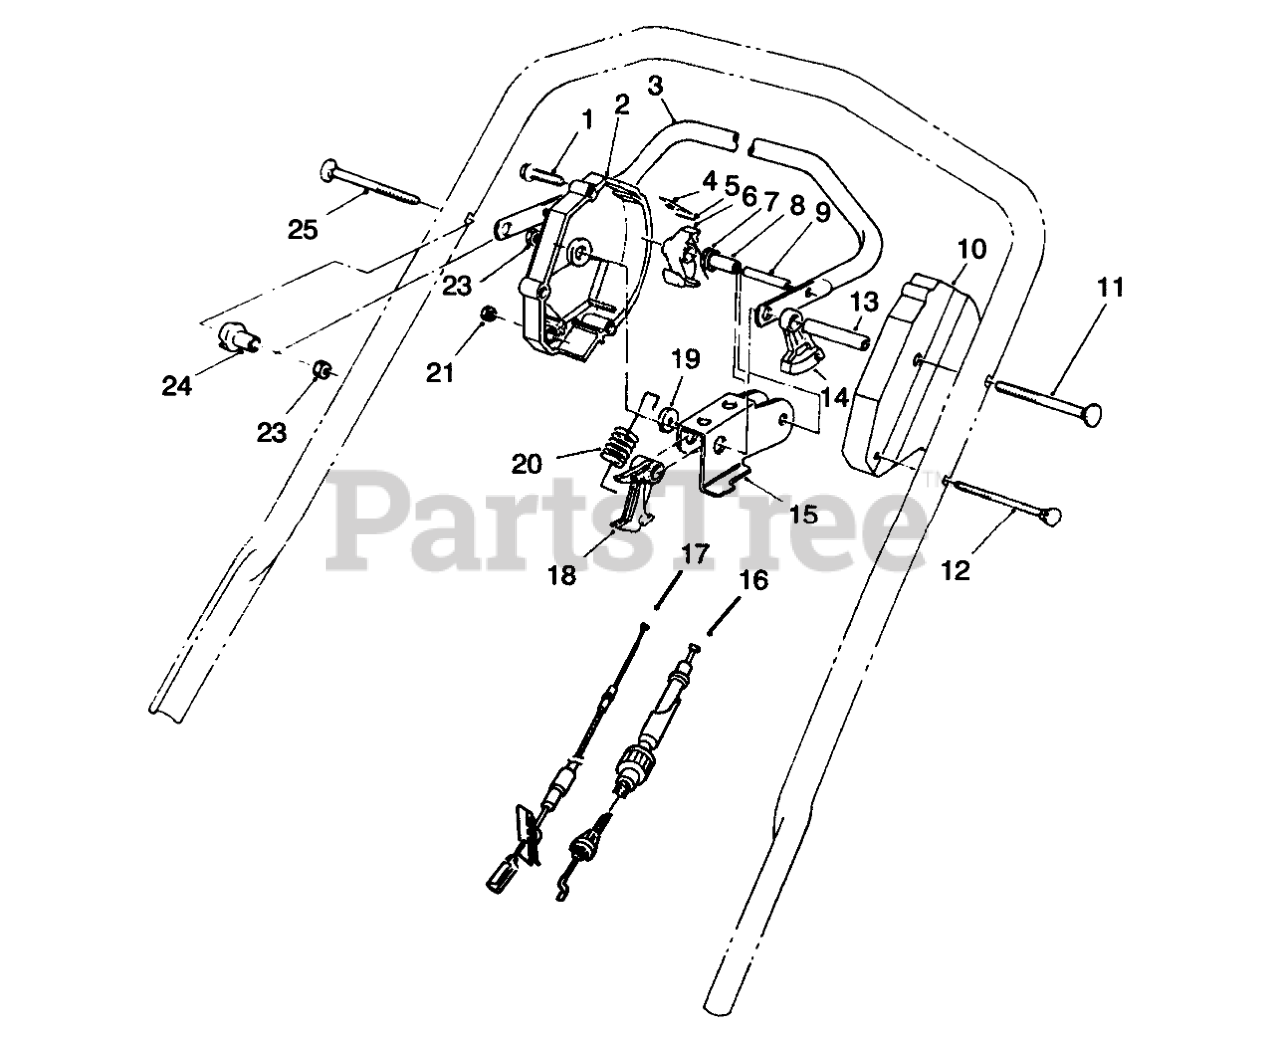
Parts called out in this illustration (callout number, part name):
1	SCREW-HWHTF
2	Housing-Control
3	Bar-Control
4	SPRING-LEAF
5	PIN-INSERT
6	HOOK-CONTROL
7	SPRING-TORSION
8	SPACER
9	PIN-ROLL, SLOTTED
10	HOUSING-CONTROL, LH
11	Screw-Handle
12	HANDLE SCREW
13	TUBING-SPACER
14	LEVER-TRACTION
15	ROCKER
16	CABLE - TRACTION
17	CABLE - BRAKE
18	LEVER-CABLE
19	WASHER-NYLON
20	SPRING-DETENT
21	NUT-HEX
23	NUT-LOCK, NI
24	SPACER-SUPPORT
25	SCREW-HANDLE
